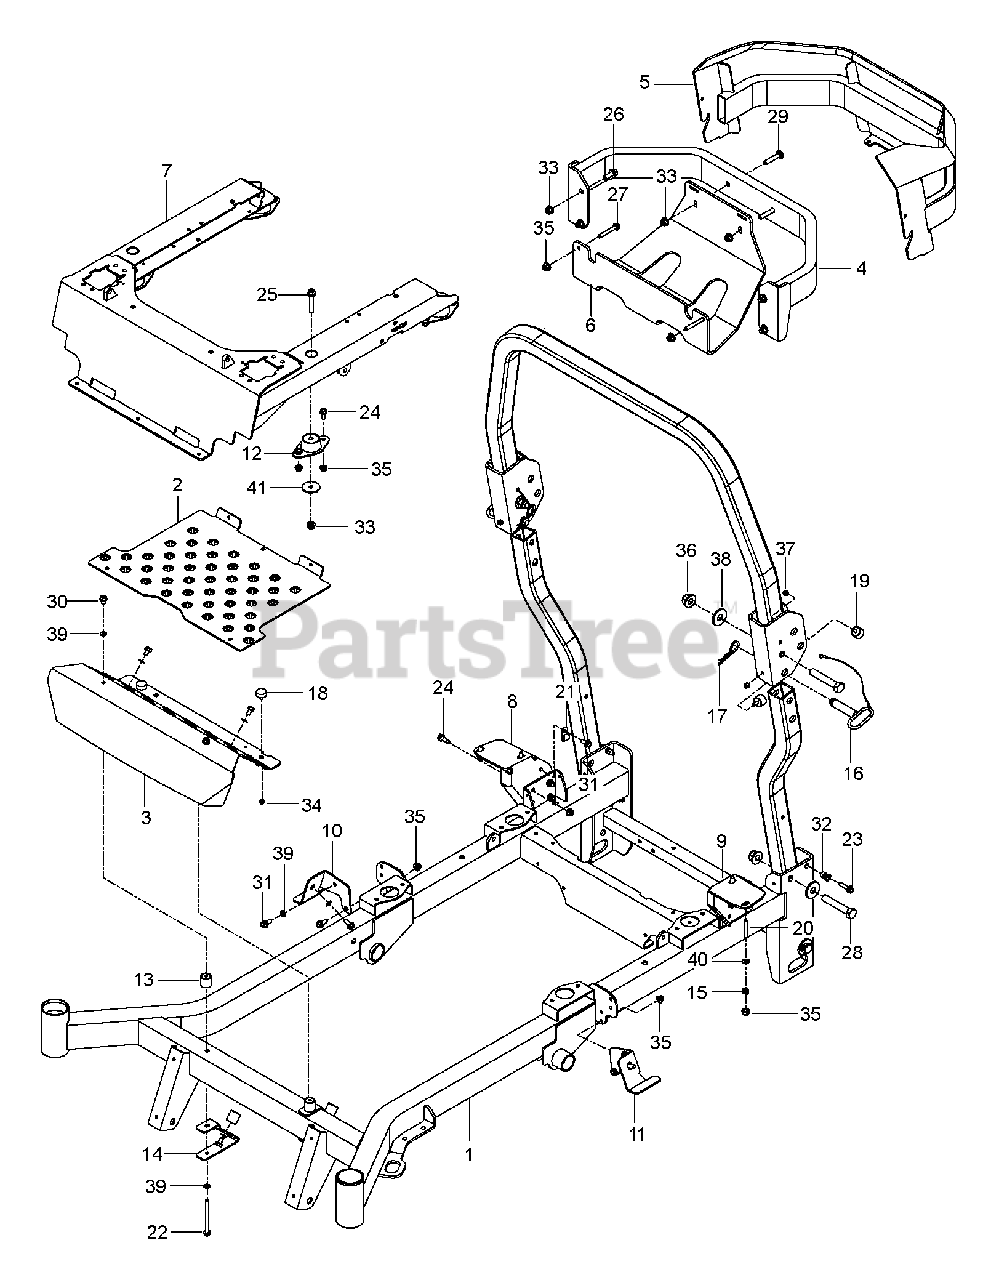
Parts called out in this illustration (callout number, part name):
1	FRAME W/DECALS, PZ
2	PLATE, FLOOR PAN, OR
3	PLATE, FOOT REST, OR
4	BUMPER.REAR.ORANGE
5	GUARD.PNT.ENGINE.GREY
6	PLATE, SKID GRAY
7	FRAME SEAT MOUNT ORANGE
8	MOUNT, RT TANK, BLK
9	MOUNT, LT TANK, BLK
10	MOUNT, TANK, RT-BLK
11	MOUNT, TANK, LT-BLK
12	MOUNT, ISO
13	MOUNT, F/F INSERT
14	BRACKET, REST MOUNT
17	PIN HAIR .148 X 2-15/16 #210
18	BUMPER, 1/4-20 STUD, 1/4
19	BUMPER, MALE STUD, 1/4-20
20	STUD, 5/16C
21	DOUBLE TUBE CLAMP
22	HHFS 5/16-18 X 3 3/4
23	HHFS 5/16-18 X 1.25 TPBLT GD 5
24	HHFS 5/16-18 X 3/4
25	HHFS 3/8-16 X 2.0 GD 5
26	HHFS 3/8-16 X 1 GRD 5 ZD
27	HHFS 5/16-18 X 2.25 GD 5
28	5/8-11 X 3-1/2 HHB GRADE 5
29	RHSNB 3/8C X 2
30	SCREW LT
31	SCREW
32	NUTSERT 5/16-18 THICK GRIP
33	NUT 3/8-16 HEX FLG NYLOC ZD
34	JAM NUT 1/4C (2 2 PW01)
35	5/16-18 NYLOC FLANGE NUT
36	NUT 5/8-11 FLG NYLOC ZD
37	LOCKNUT.NYLOC.1/4-20
38	WASHER, 5/8 FLAT
39	WASH 5/16 DISC SPRING ZD
40	WASHER
41	WASHER, 3/8 SPEC
